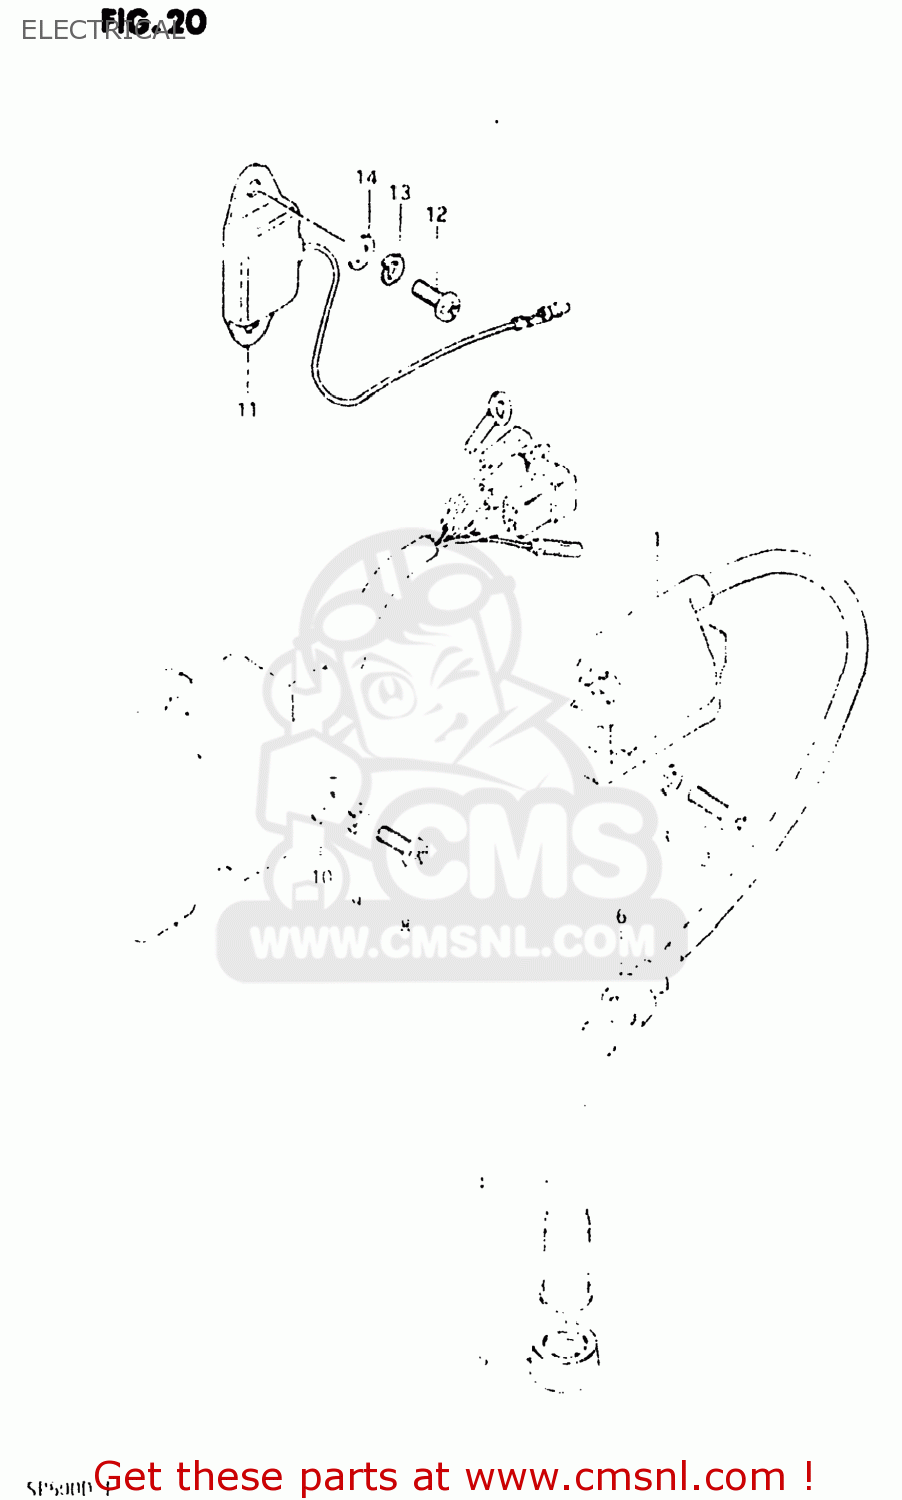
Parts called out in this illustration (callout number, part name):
1	COIL ASSEMBLY,IGNITION
2	SCREW
3	LOCK WASHER
4	CAP ASSY,SPARK PLUG
5	SEAL,SPARK PLUG
6	SEAL,SPARK PLU
7	CDI UNIT
8	SCREW
9	LOCK WASHER
10	WASHER (6.5X18X1.6)
11	REGULATOR ASSEMBLY,VOLTAGE
12	SCREW
13	LOCK WASHER
14	WASHER
